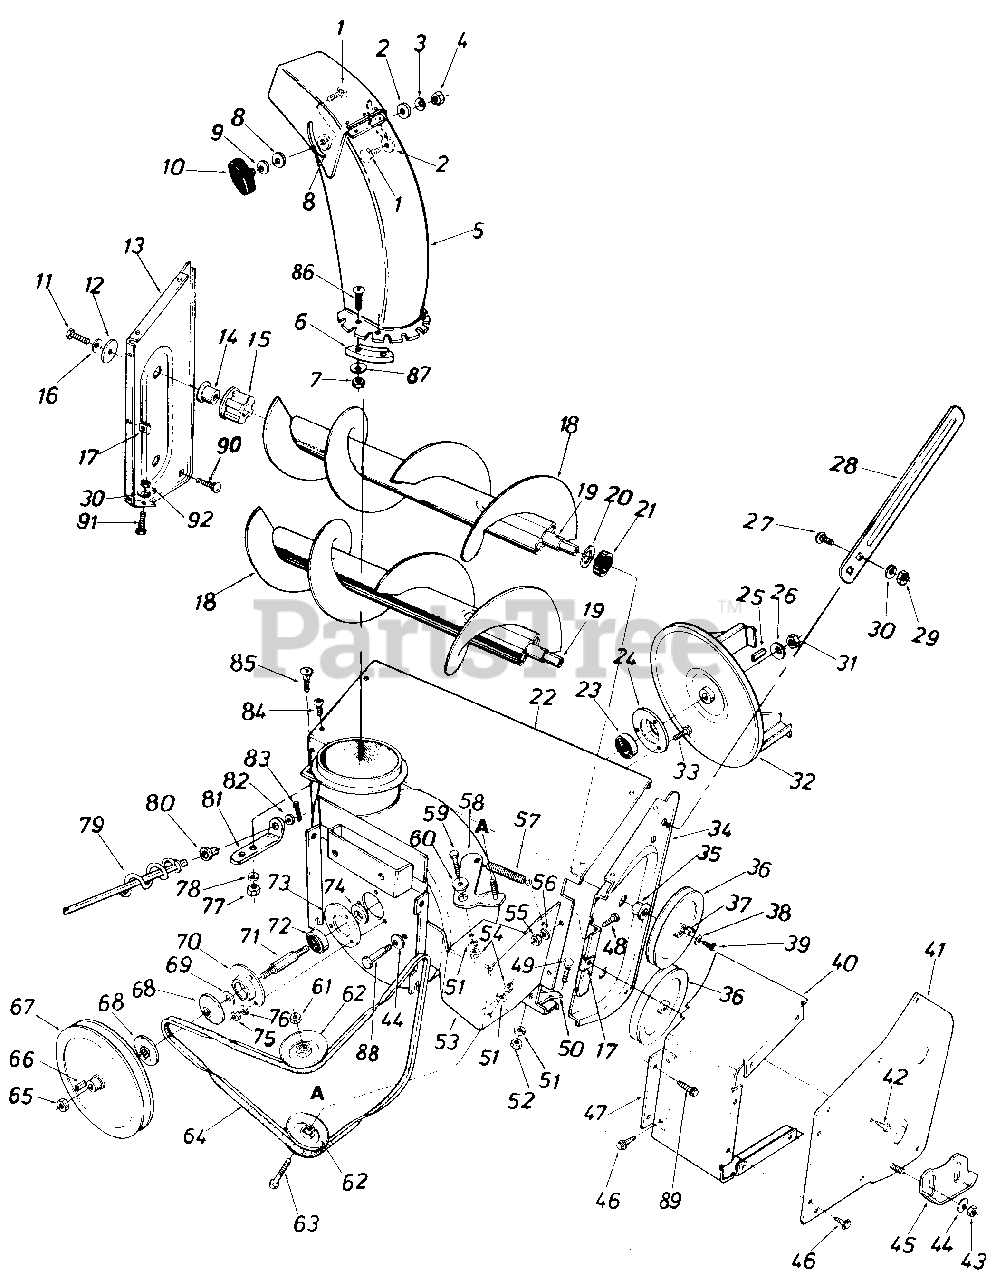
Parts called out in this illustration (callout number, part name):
1	Carriage Bolt 5/16-18 x 1.0" Lg.
2	Fl-Wash. .344" I.D. x 1.125" O.D.
3	Bell-Wash. .345" I.D. x .88" O.D.
4	Hex Cent. L-Nut 5/16-18 Thd.
5	Blower Chute Ass'y.
6	Chute Flange Keeper
7	Hex Patch L-Nut 1/4-20 Thd.
8	Fl-Wash. .531" I.D. x 1.25" O.D.
9	Bell-Wash. .345" I.D. x .88" O.D.
10	Knob Handle Ass'y.
11	Hex Bolt 5/16-18 x 1.0" Lg. (Grade 5)
12	Fl-Wash. .32" I.D.
13	Spiral Housing Plate L.H.
14	Shaft Pin 1.0" O.D. x .94
15	Tubing Support Brg.
16	Bell-Wash. .345" I.D. x .88" O.D.
17	Speed Clip 1/4-20
18	Auger Ass'y. 22" x 6" Dia.
20	Fl-Wash. .760" I.D. x 1.75" O.D.
21	Spacer 1.25" I.D. x 1.50" O.D. x .58" Thk.
22	22" Spiral Housing Ass'y.
23	Ball-Brg. .787" I.D. x 1.85" O.D. x .551
24	Bearing Housing 1.85" I.D.
25	Sq. Key 3/16 x 1.50" Lg.
26	Bell-Wash. .630" I.D. x 1.25" O.D.
27	Carriage Bolt 5/16-18 x .62" Lg.
28	Guide Blade
29	Hex Nut 5/16-18 Thd.
30	L-Wash. 5/16" I.D.
31	Hex Jam Nut 5/8-18 Thd.
32	11" Dia. Blower Fan Ass'y.
33	Hex Bolt 5/16-18 x 1.00" Lg.
34	Spiral Housing Plate R.H.
35	Hex Flange Brg. .751" I.D.
36	3/8" V-Pulley 518" I.D. x 5.5" 0. D.
37	Sq. Key 3/16" X .75" Lg.
38	Bell-Wash. .265" I.D. x .75" O.D.
39	Hex Bolt 1/4-20 x .62" Lg.
40	Belt Cover Top
41	Belt Cover Side Ass'y.
42	Hex Bolt 3/8-16 x .751' Lg.
43	Hex Jam Nut 3/8-16 Thd.
44	Bell-Wash. .400" I.D. x .88" 0. D.
47	Support Bracket
48	Hex Bolt 5/16-18 x .50" Lg.
49	Carriage Bolt 5/16-18 x .62" Lg.
50	Scraper Bar Kit 22"
51	Bell-Wash. .345" I.D. x .88" O.D.
52	Hex Nut 5/16-18 Thd.
54	Hex Nut 3/8-24 Thd.
55	Hex Nut 5/16-18 Thd.
56	L-Wash. 5/16" I.D.
57	Extension Spring .620" O.D. x 3" Lg.
58	Idler Bracket Ass'y.
59	Hex Bolt 3/8-24 x .75" Lg.
60	Shld. Spacer .625" I.D.
61	Hex Ins. L-Nut 3/8-24 Thd.
62	"V"-Idler 2.62" O.D.
63	Hex Bolt 3/8-24 x 1.25" Lg.
64	V-Belt
65	Hex Cent. L-Nut 5/8-18 Thd.
66	Sq. Key 3/16 x .75" Lg.
67	5/8" I'V"-Pulley .628" I.D. x 7.50" O.D.
68	3/8" "V"-Pulley Half .625" I.D. x 2.25" O.D.
69	Fl-Wash. .635" I.D. x 1.12" O.D.
70	Open Brg. Housing Ass'y.
71	Fan Spindle
72	Ball Brg. .787" I.D. x 1.85" O.D.
73	Open Brg. Housing 1.85" I.D.
74	Spacer .790" I.D. x 1.0" O.D.
75	Hex Nut 5/16-18 Thd.
76	L-Wash. 5/16" I.D.
77	Hex Nut 5/16-18 Thd.
78	L-Wash. 5/16" I.D.
79	Chute Crank Ass'y. R.H. 39.0" Lg.
80	Plastic Bushing .380" I.D.
82	Fl-Wash. .385" I.D. x .62" O.D.
83	Cotter Pin 3/32" Dia. x .75" Lg.
84	Truss Mach. Scr. 1/4-20 x .50" Lg.
85	Carr. Bolt 5/16-18 x .75" Lg.
86	Truss Mach. Scr. 1/4-20 x .75"
87	Fl-Wash. .265" I.D. x .75" O.D. x .062
88	Shld. Bolt .5" Dia. x 2.11" Lg.
89	Hex Wash. Hd. Tap Scr. 5/16-24 x .5" Lg.
90	Carriage Bolt 3/8-16 x .62" Lg.
91	Hex Bolt 5/16-24 x .5" Lg.
92	Hex Nut 5/16-24 Thd.
